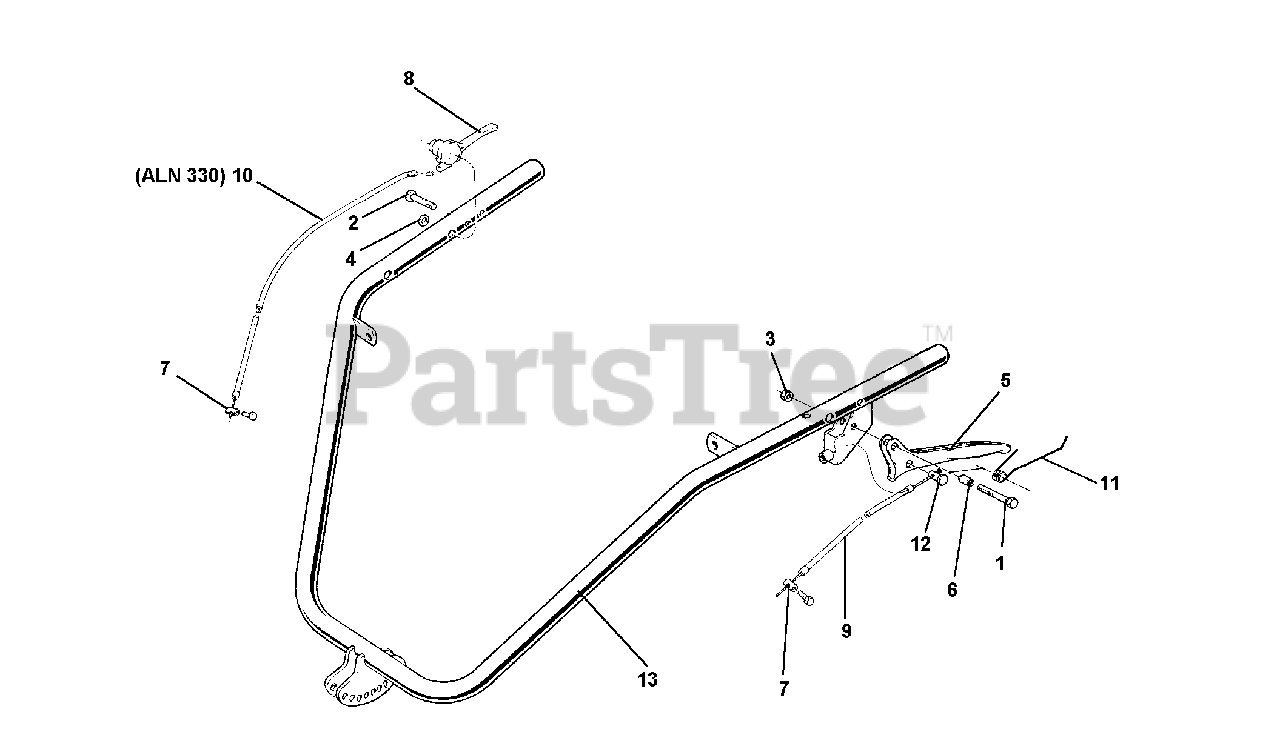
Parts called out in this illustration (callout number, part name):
1	SCREW M6 X 25
2	SCREW M6 X 40
3	NUT, SELF LOCKING M6
4	WASHER, LOCK 8.4
6	LEVER SPACER
7	CLAMP, CABLE
8	LEVER, ACCELERATOR
9	CABLE & SHEATH, CLUTCH
10	WIRE, SHEATH 1850 GAS
11	LEVER SPRING
